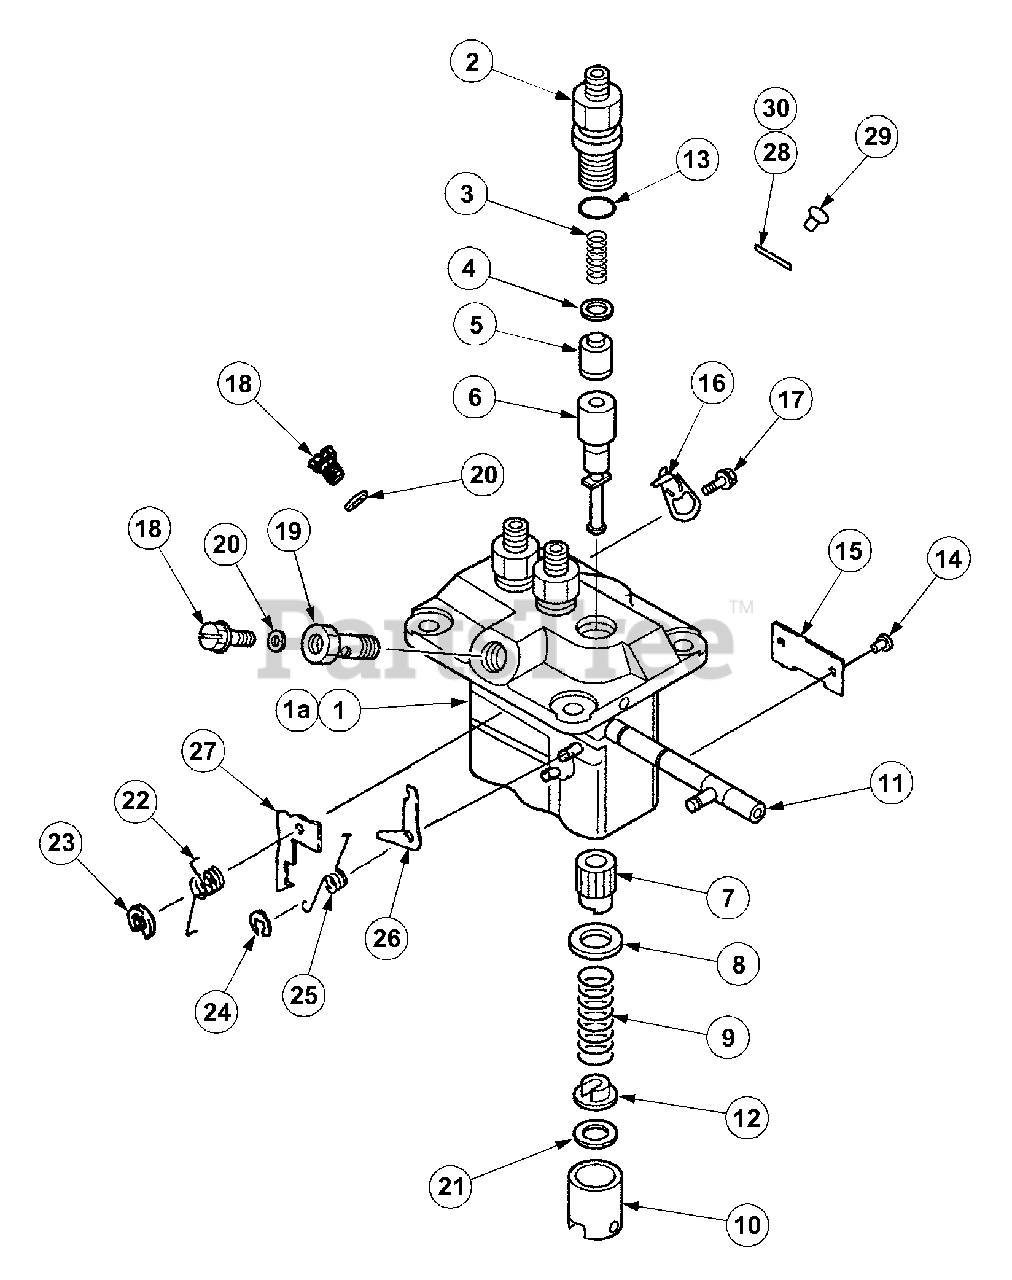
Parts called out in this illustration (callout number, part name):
1	Housing Sub Ass'y.
1A	Housing Sub Ass'y.
2	Holder,Delivery
3	Spring,Delivery
4	Gasket,Delivery
5	Valve Sub Ass'y.
6	Element Sub Ass'y.
7	Sleeve,Control
8	Seat,Spring
9	Spring,Plunger
10	Tappet Sub Ass'y.
11	Rack Assy,Control
12	Seat,Spring
13	O-Ring
14	Pin,Tappet
15	Plate
16	Plate,Adjusting
17	Bolt,Washer Head
18	Screw,Air Bleed
19	Screw,Hollow
20	Washer,Pipe Union
21	Plate,Tappet Shim
22	Spring,Smoke Set
25	Spring,Angleich
26	Plate,Angleich
27	Plate,Smoke Set
28	Plate,Name
29	Rivet,Serration
30	Plate,Name
